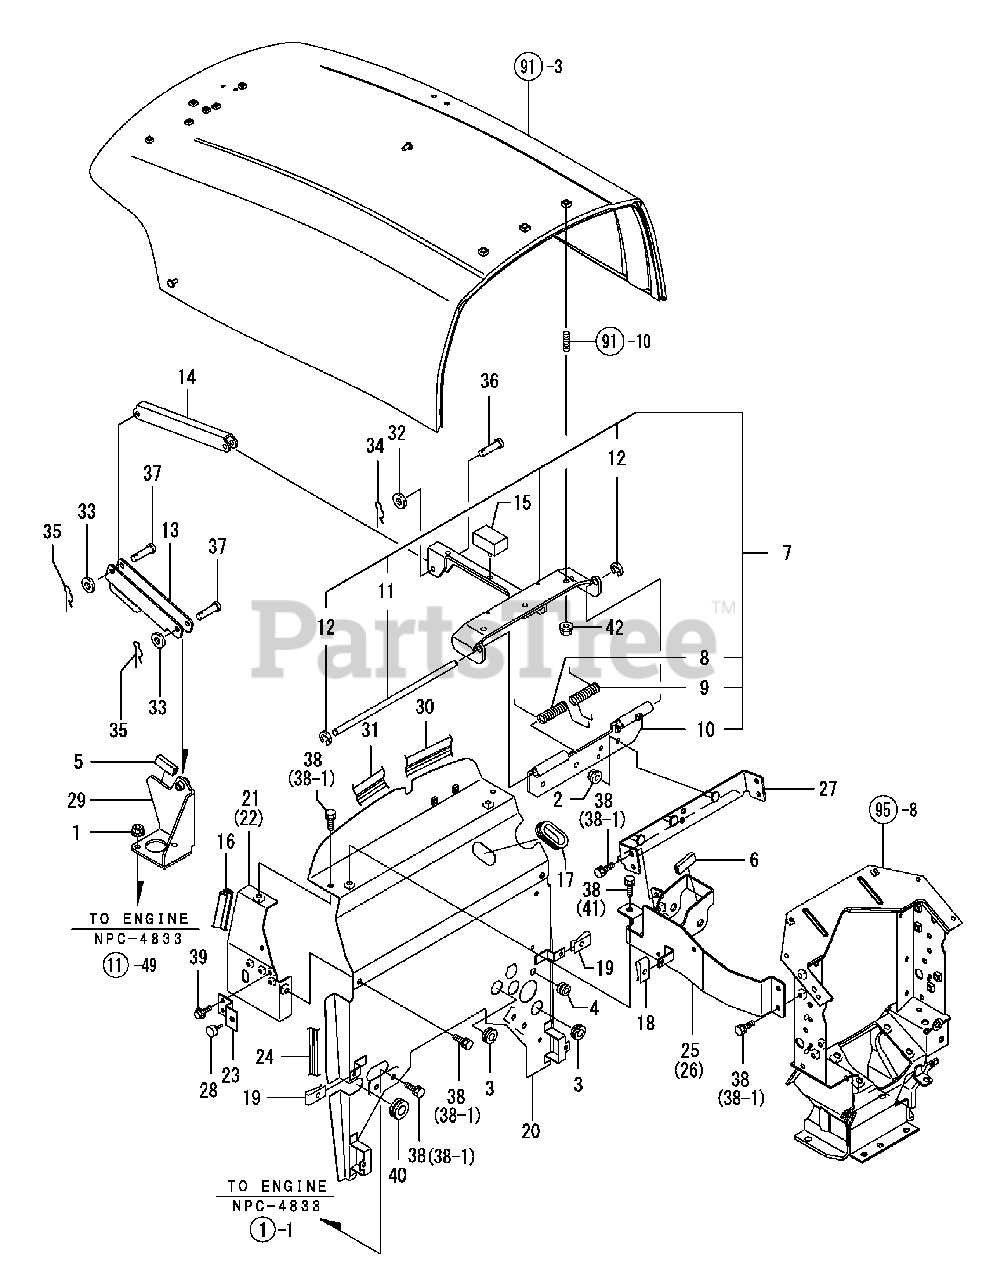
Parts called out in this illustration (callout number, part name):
1	NUT W/WASHER 8
2	NUT W/WASHER 8
3	GROMMET, 25
7	HINGE ASSY, HOOD
16	WEATHER STRIP, 180
17	GROMMET, 21X46
18	NUT, M5
19	NUT, M5
20	PLATE CMP, AIR SHIELD
21	SUPPORT L.H., CMP
22	SUPPORT R.H., CMP
25	BRACKET L CMP, TANK
26	BRACKET R CMP, TANK
27	SUPPORT CMP, HOOD
28	STOPPER, PEDAL
29	STAND CMP, HOOD
30	WEATHER-STRIP, 195
31	STRIP 250, WEATHER
32	WASHER 8, POLISHED
33	WASHER 8, POLISHED
34	SNAP PIN (JASO 8)
35	SNAP PIN (JASO 8)
38	BOLT M 8X 16 PLATED
38-1	BOLT M 8X 16 PLATED
39	BOLT M 6X 12 PLATED
41	BOLT M 8X 12 PLATED
42	NUT W/WASHER 8
